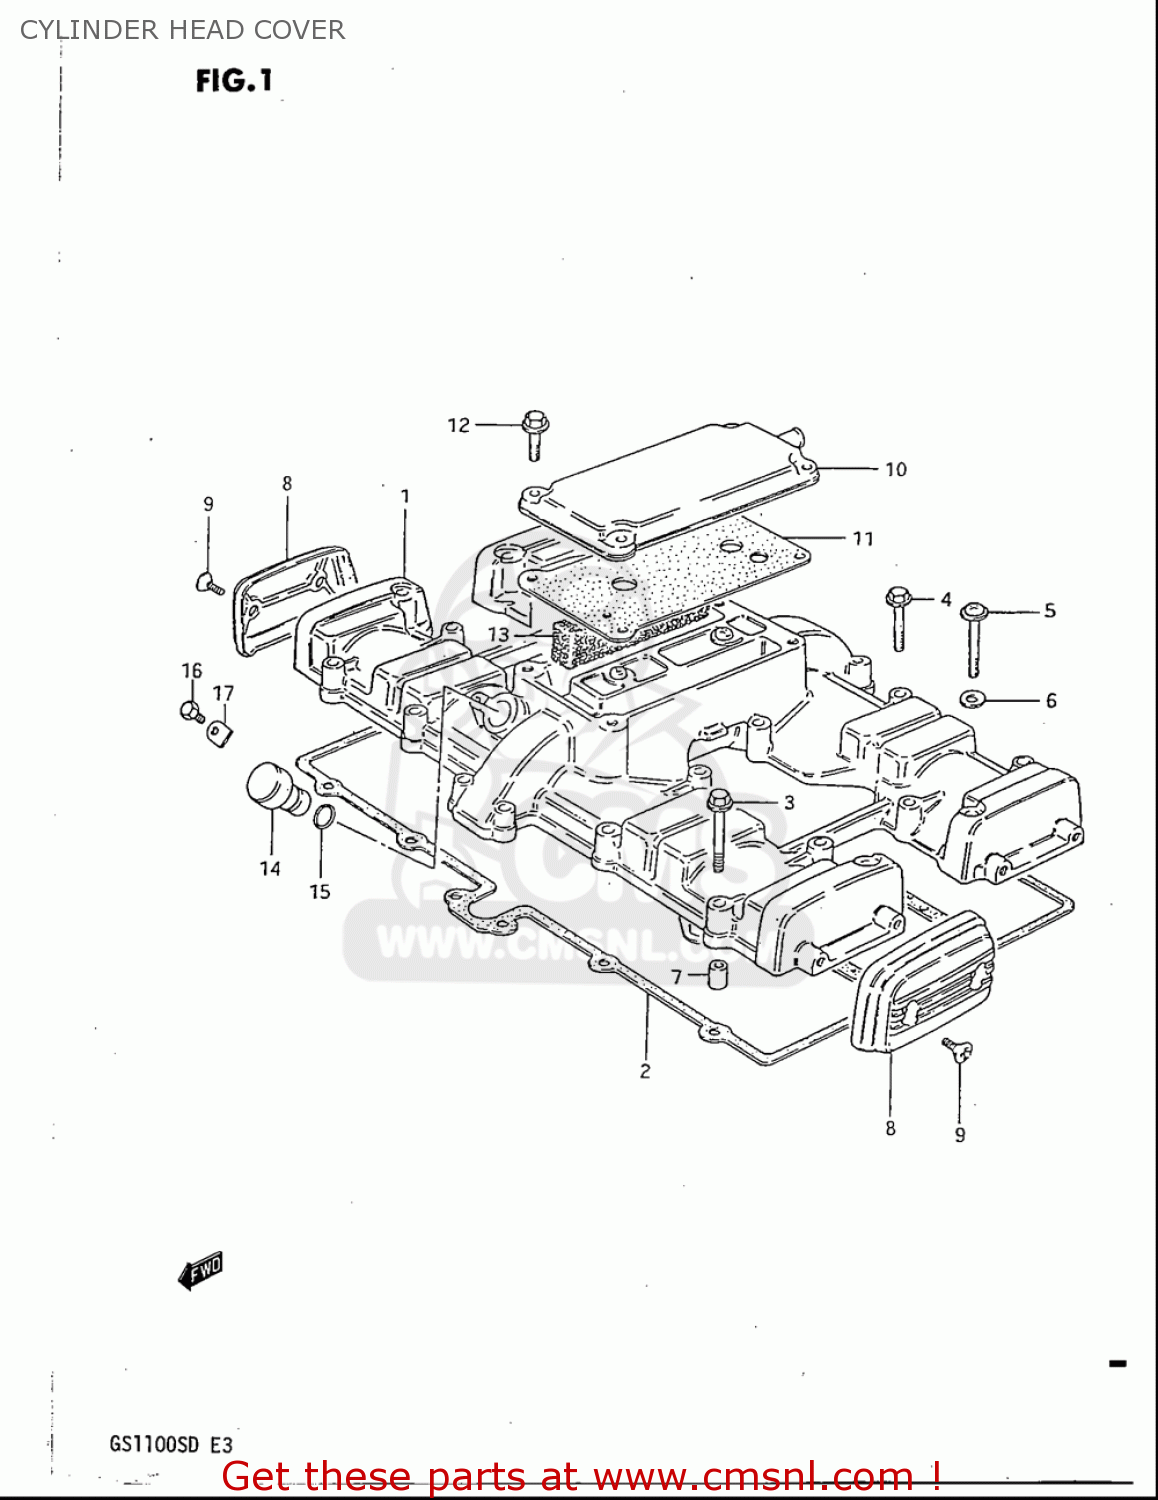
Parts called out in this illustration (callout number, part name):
1	COVER,CYLINDER HEAD
2	GASKET,CYLINDER HEAD COVER (NAS)
3	BOLT
4	BOLT
5	SCREW
6	GASKET(5.8X13X1.2) (NAS)
7	PIN(6.2X8X11)
8	CAP,CYLINDER HEAD COVER
9	SCREW(5X12)
10	COVER,BREATHER
11	GASKET,BREATHER COVER (NAS)
12	SEPARATOR,HEAD COVER OIL
13	BOLT
14	PLUG,TACH GEAR SLEEVE HOLE
15	SEAL,TACHOMETER DRIVEN
16	SCREW(5X12)
17	PLATE,TACH DRIVE GEAR SLEEVE
